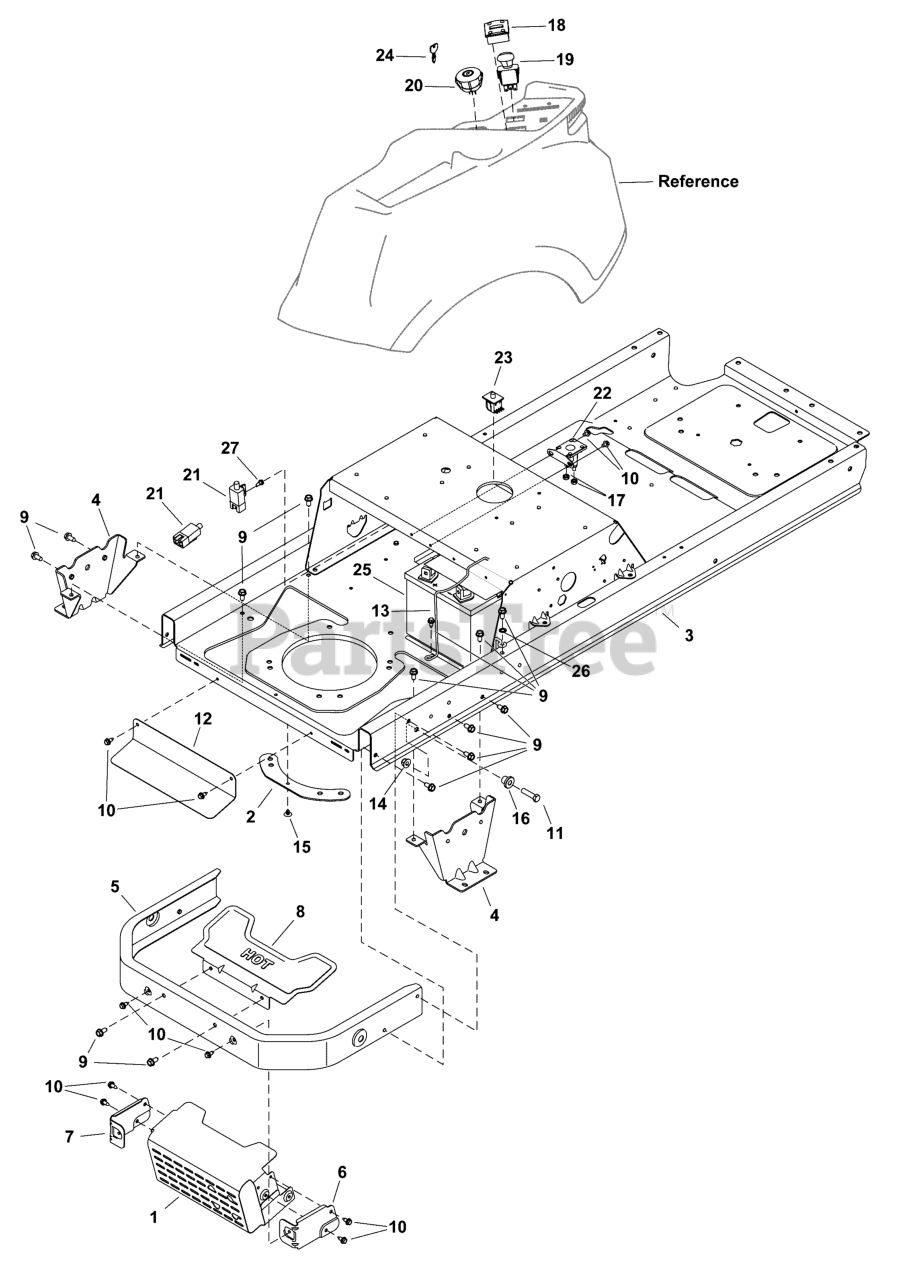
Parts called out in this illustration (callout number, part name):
1	ASSEMBLY, Muffler Shield
2	PLATE, Retainer
3	ASSEMBLY, Frame
4	BRACKET, Transmission Mounting
5	BUMPER, Rear
6	BRACKET, Muffler Mounting Shield, RH
7	BRACKET, Muffler Mounting Shield, LH
8	SHIELD, Muffler
9	SCREW, 5/16-18 X .750, Hex Washer
10	SCREW, 1/4-20 X .625, Hex Washer
11	SCREW, 3/8-16 X 1.25, Hex
12	SHIELD, Lower Heat
13	ROD, Battery
14	NUT, 3/8-16, Flanged Lock, GR5
15	CLIP, .250 DIA. X .500 LG
16	SPACER, .38 X 1.0 X .70, Shoulder
17	NUT, Flange Nylock , 1/4-20
18	HOUR METER/SERVICE MINDER
19	SWITCH, Electric PTO
20	SWITCH, Key Ignition
21	SWITCH, Interlock
22	SOLENOID
23	SWITCH, Seat
24	ASSEMBLY, Key
25	BATTERY
26	WASHER, 5/16, EXT., Lock
27	SCREW, #10-32 X .500, Shoulder
